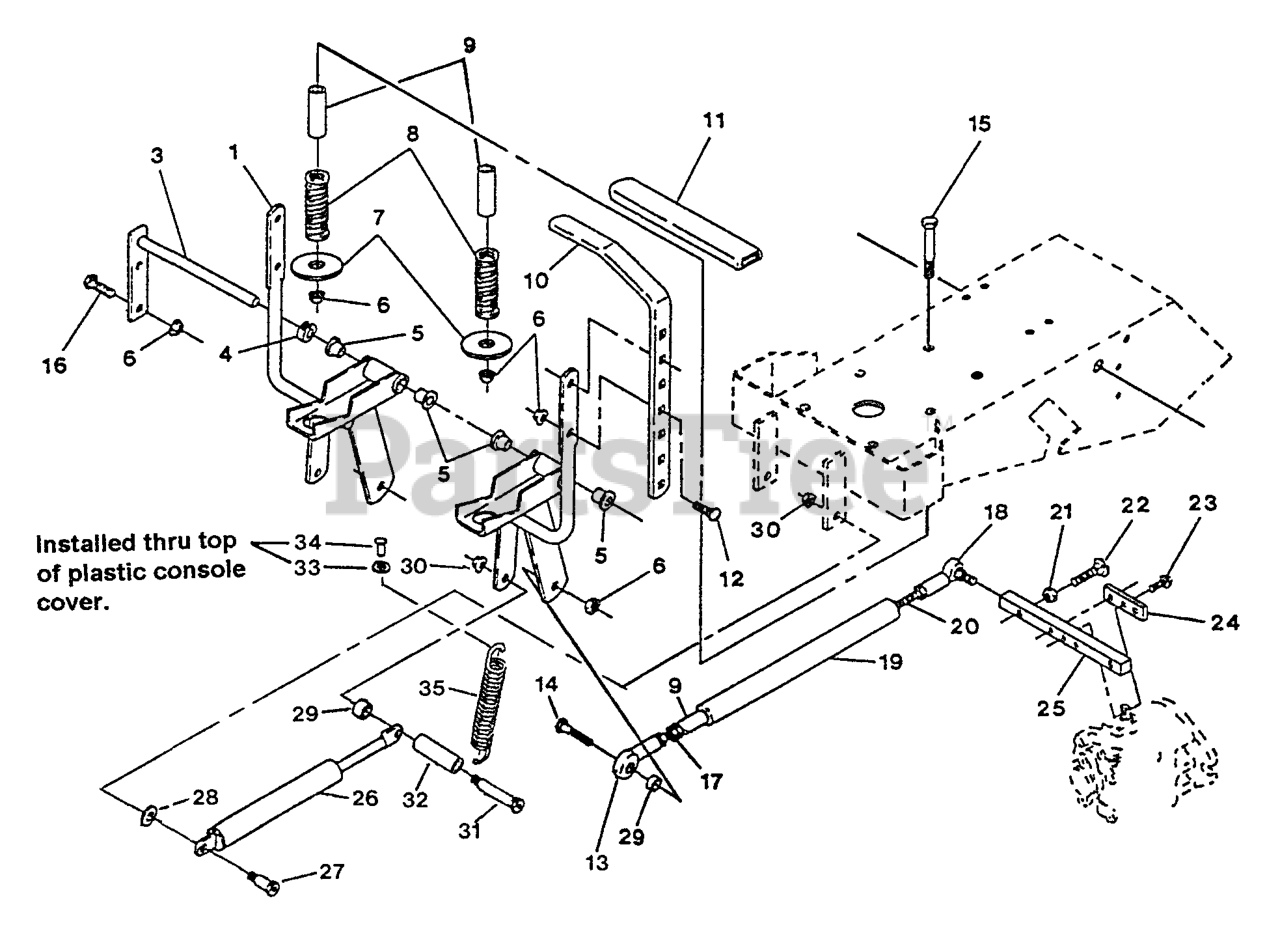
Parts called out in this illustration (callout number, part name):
5	BEARING-CONTROL
7	WSHR,REVERSE INDICATOR
8	SPRING-INDICATOR, REVERSE
9	BUSHING,SPRING GUIDE
11	GRIP,MOTION CONTRL
13	BALLJOINT-RH
18	BALLJOINT
20	ROD,STEERING
24	PLATE,CLAMP
25	ARM,PUMP CONTROL
29	SPACER-PLATED
32	SPACER,MOTION CONTRL PLT
35	SPRING,EXTENSION
